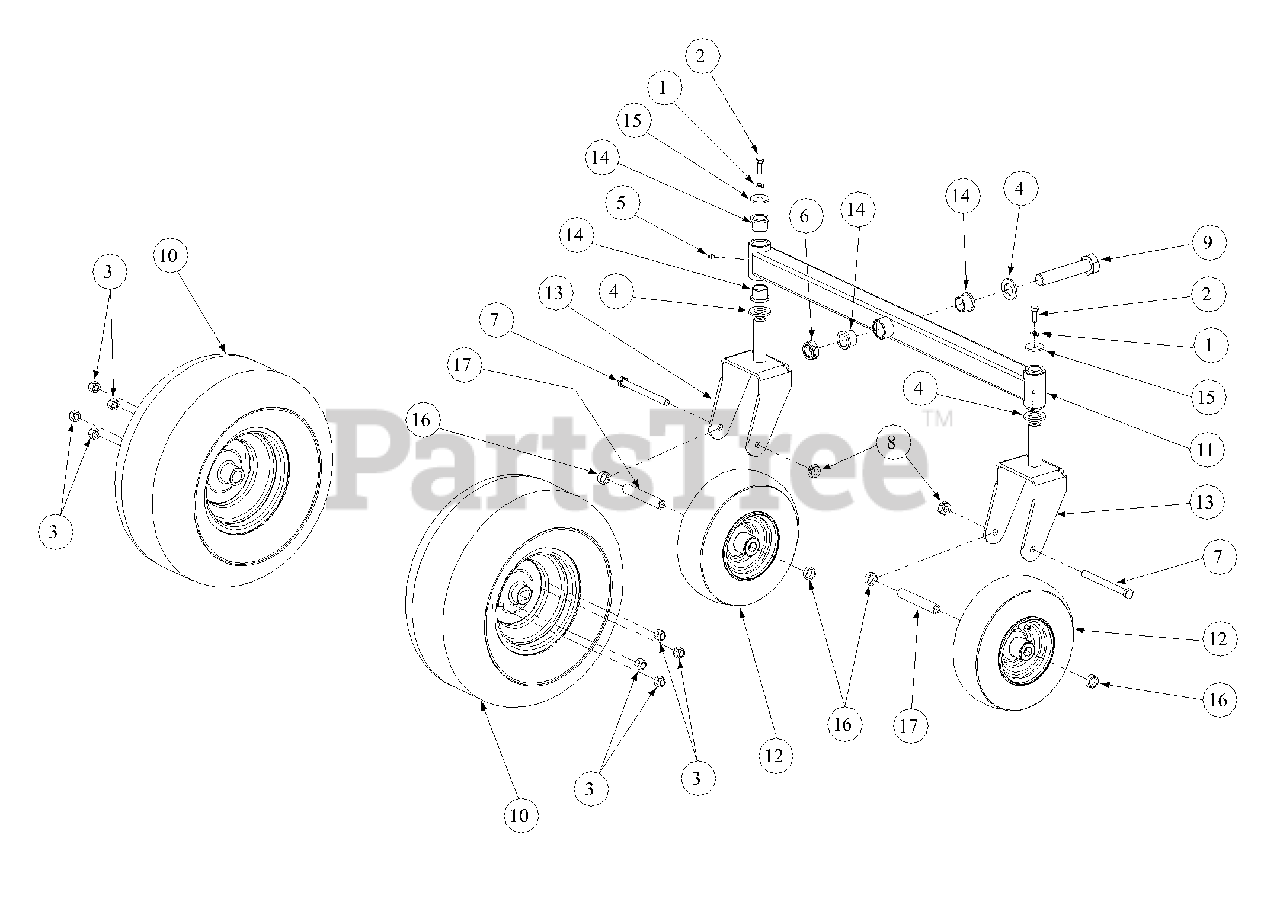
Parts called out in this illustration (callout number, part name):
1	Lock Washer, 3/8 Zinc
2	Hex Cap Screw, 3/8-16 x .88
3	Lug Nut, 1/2-20
4	Washer Special
5	Grease Fitting, 1/4-28 x 3/16
6	Nut Jam, 1.0-14, Nylon Insert
7	Hex Cap Screw, 1/2-20 x 5.50
8	Nut, 1/2-20, Center Lock
9	Hex Cap Screw, 1-14 x 5.0
10	Wheel Assembly, 18 x 6.5
11	Front Axle Assembly
12	Front Wheel Assembly
13	Castor Wheel Mounting Bracket
14	Flange Bearing, 1.0 ID
15	Flat Washer, .390 x 1.5 x .134
16	Spacer, .790 ID x .347 Lg
17	Wheel Spacer
